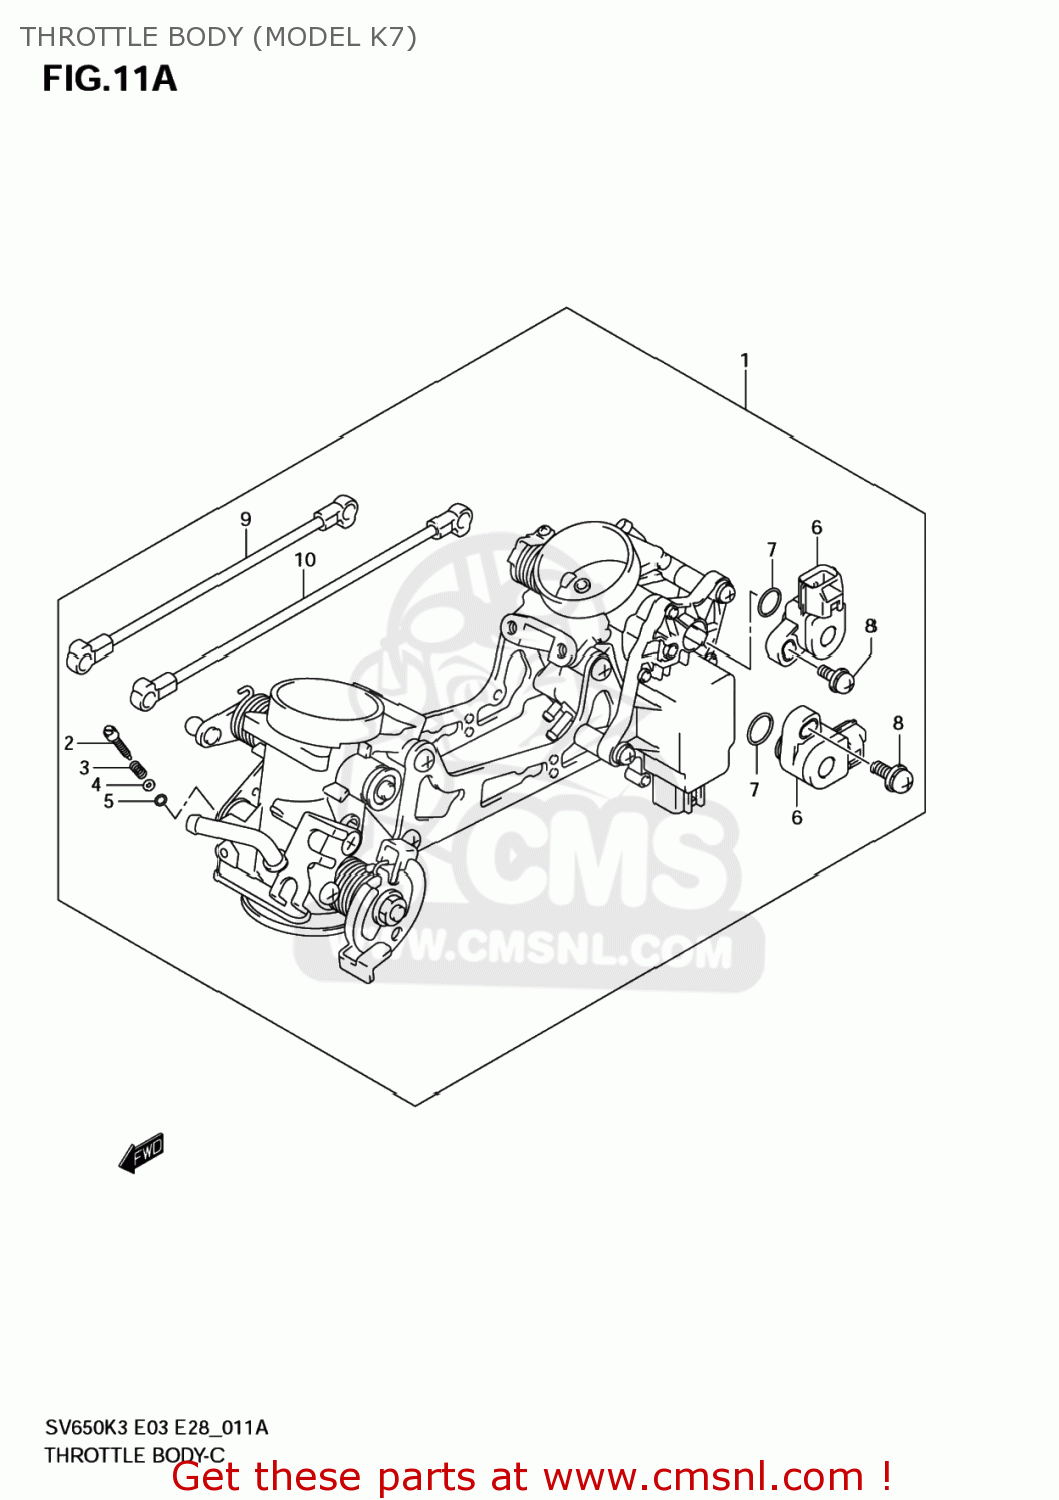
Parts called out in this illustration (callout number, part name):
1	BODY ASSY,THROTTLE
2	SCREW
3	SPRING,THROTTLE SCREW
4	WASHER
5	O RING,PILOT AIR SCREW
6	SENSOR
7	O RING
8	SCREW
9	ROD ASSY
10	ROD ASSY
